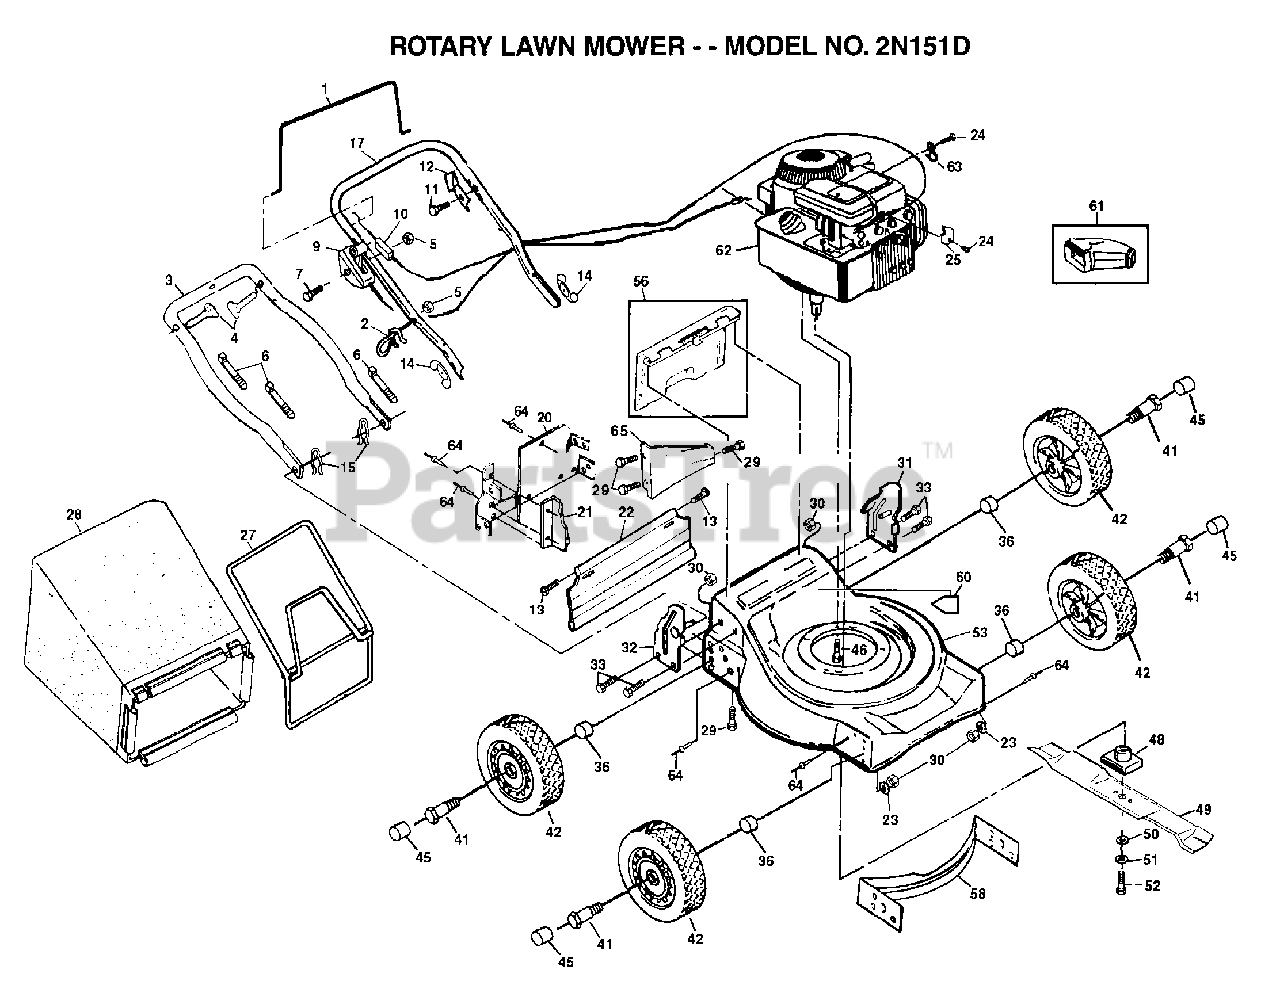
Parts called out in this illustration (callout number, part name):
1	CONTROL BAR PM
2	ROPE GUIDE
4	BOLT.HANDLE.LM
7	SCREW.HXHD.WASH.
9	CONTROL THROTTLE
10	"CABLE,ENG ZONE CO"
11	TAPPING SCREW
12	"BRKT,UPSTOP"
13	HINGE SCREW
14	"NUT,WING PM"
15	HAIRPIN COTTER
20	PLATE.BACK.20RD
22	SKIRT.REAR.20RD.
23	WASHER PM
24	SCREW PM
25	CABLE CLAMP
27	FRAME.CATCHER.ASM
28	GRASS BAG
29	SCREW
30	LOCKNUT PM
31	HANDLE BRKT LH
33	SCREW.HXWS.5/16
41	AXLE BOLT
42	WHEEL.ASM
45	HUB CAP-PLASTIC
46	BOLT.ENG.3/8-16
48	BLADE ADAPTOR
49	BLADE.20.MULCH.AY
50	"WASHER,HARDEN"
51	LOCKWASHER
52	SCREW
56	KIT.DOOR.RR.20STL
60	DECAL HYT
63	GUIDE CLIP PM
64	BLIND RIVET
65	REAR BAFFLE
